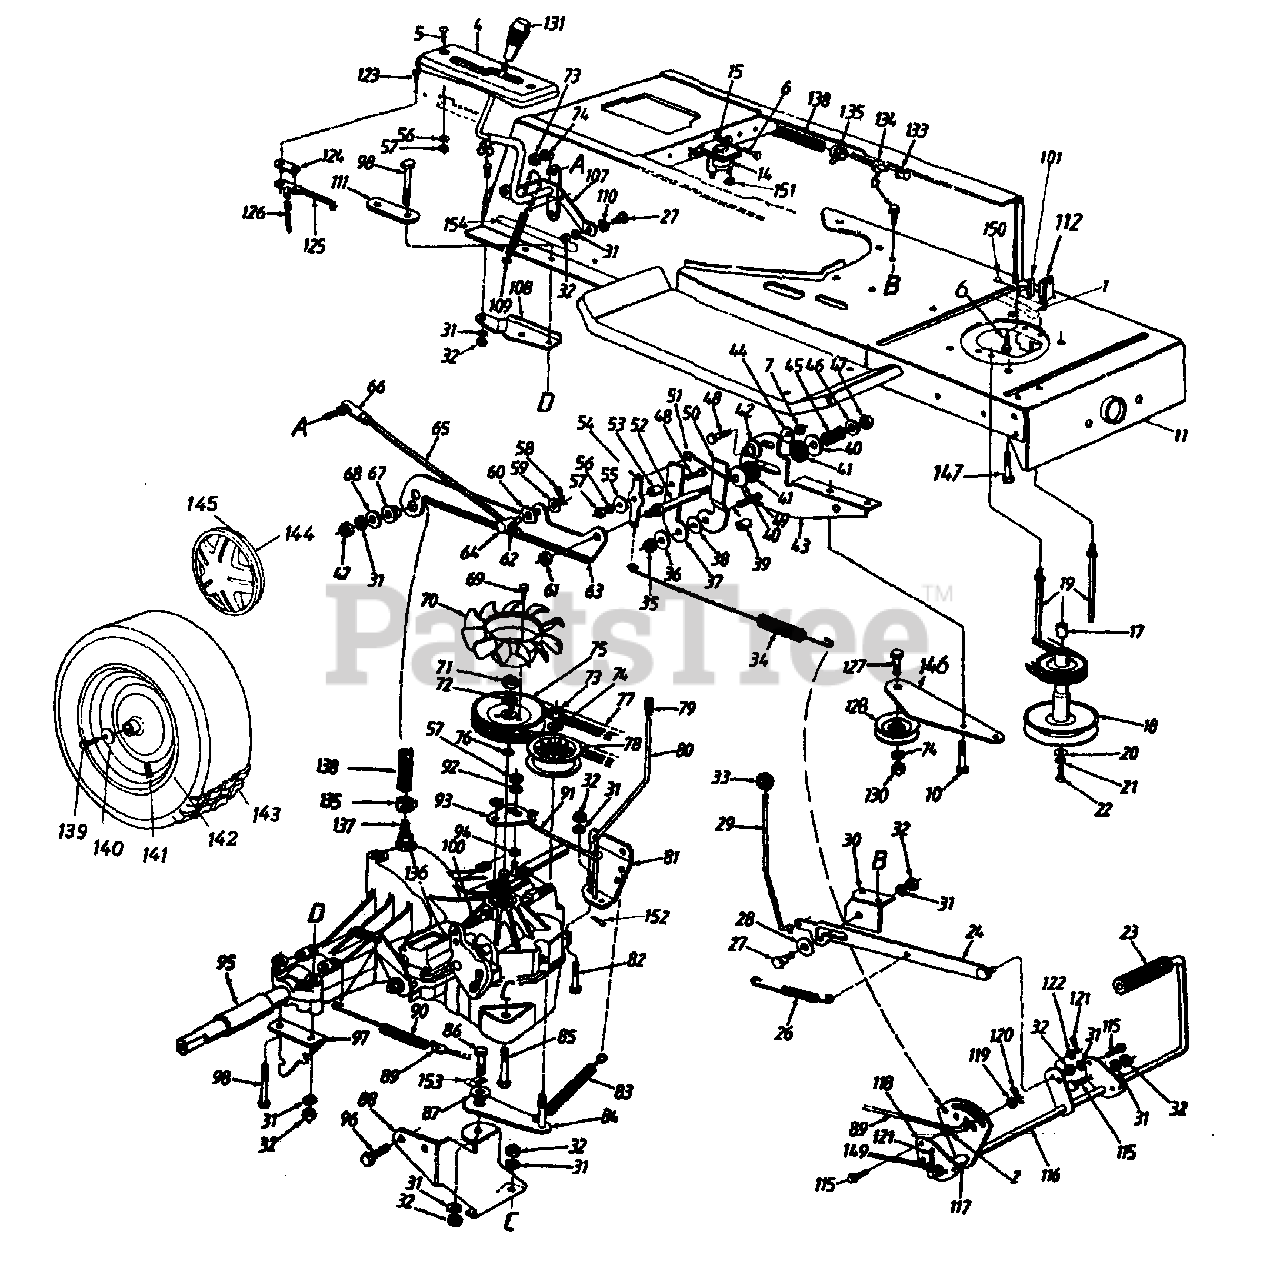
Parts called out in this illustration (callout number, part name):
1	Spring Switch
2	Hex Sems Nut 5/16-18 Thd.
4	Index Bracket
5	Pan Hd. Mach. Scr. 1/4-20 x .75"
6	Hex Wash. Hd. TT-Tap Scr.
7	Hex Nut 1/4-28 Thd.
10	Hex. Bolt 1/4-28 x .62" Lg.
14	Solenoid
15	Ext. L-Wash. 1/4" I.D.
18	Engine Pulley
19	Belt Guard Stud 4.75" Lg.
20	Fl-Wash. 7/16" I.D. x 1.25" O.D.
21	L-Wash. 7/16" I.D.
22	Hex Bolt 7/16-20 x 1.25" Lg.
23	Foot Pad
27	Shld. Bolt .437" Dia. x .268"
28	Fl-Wash. 7/16" I.D. x 1-3/8" O.D.
29	Lock-up Rod
31	L-Wash. 5/16" I.D.
32	Hex Nut 5/16-18 Thd.
33	Ball Knob
34	Neutral Return Spring
35	Hex Nut 5/16-24 Thd.
36	Fl-Wash. .344" I.D. x 1" O.D.
37	Scissor-Flat
38	Fl-Wash. .33" I.D. x 1.25" O.D.
40	Bell-Wash. .4" I.D. x 1.13" O.D.
41	Friction Washer
42	Centering Gauge Spacer
43	Neutral Return Mtg. Brkt.
44	Bell-Wash. .265" I.D. x.75" O.D.
45	Comp. Spring 1.19" Lg.
46	Fl-Wash. .26" I.D. x .72" O.D.
47	Hex Nut 5/16-24 Thd.
48	Hex Bolt 1/4-28 x 1" Lg. (Gr. 5)
49	Rib Neck Bolt 5/16-24 x .84" Lg.
50	Scissor-Offset
51	Neutral Return Rod
52	Friction Disc Stud
53	Shld. Spacer
54	Neutral Return Lever
55	Fl-Wash. .265" I.D. x 1" O.D.
56	L-Wash. 1/4" I.D.
57	Hex Nut 1/4-20 Thd.
58	Hairpin Clip
59	Fl-Wash. .375" I.D. x.87" O.D.
60	Spring Wash. .39" I.D.
61	Hex L-Nut 3/8-24 Thd.
62	Hex Jam Nut 3/8-24 Thd.
63	Neutral Return Brkt.
64	Ferrule 3/8-24 Thd.
65	Control Rod
66	Ball Joint 3/8-24 Thd.
67	Shld. Spacer .5" Dia. x .27" Lg.
68	Fl-Wash. .349" I.D. x .879" O.D.
69	Hex Tap Scr. #12 x .62" Lg.
70	Fan
71	Hex Nut 1/2-20 Thd.
72	L-Wash. 1/2" I.D.
73	Hex Nut 3/8-24 Thd.
74	L-Wash. 3/8" I.D.
75	Transmission Pulley
76	Wire Ring
77	V-Belt
78	Fl-Idler Pulley 2.75" O.D.
79	Rod End Grip
80	Bypass Control Lever
81	Transaxle Support Brkt.- L.H.
82	Hex Bolt 5/16-18 x 1.25" Lg.
83	Ext. Spring 6.12
86	Hex Bolt 5/16-18 x .75" Lg.
87	Shld. Spacer .5" Dia. x .27" Lg.
88	Transaxle Support Brkt.- R.H.
89	Brake Rod 24.94" Lg.
90	Ext. Spring
91	Bypass Actuator Rod
92	Fl-Wash. .281" I.D. x.5" O.D.
93	Bypass Adjustment Brkt.
94	External L-Wash. 1/4" I.D.
95	Sleeve .758" I.D. x 1" O.D.
96	Hex. TT-Tap Scr .5/16-18x.62"
100	Hex Bolt 5/1 6-24 x 1" Lg.
101	Hex Wash. Hd. AB-Tap Scr.
107	Speed Control Lever Ass'y.
110	Spr-Wash. .445" l.O. x.75" O.D.
112	Safety Switch (Clutch)
115	Hex TT-Tap Scr. 5/16-18 x 7/8"
120	Cotter Pin 3/32" Dia.
121	Cotter Pin 1/8" Dia.
122	Fl-Wash. .385" I.D. x .62" O.D.
123	Hex AB-Tap Scr. #8 x .5" Lg.
124	Insulator Nut Plate
125	Reverse Safety Switch
126	Extension Wire
127	Hex Bolt 3/8-16 x 1.5" Lg.
128	Idler Pulley
130	Hex Nut 3/8-16 Thd.
131	Shift Knob
134	Plastic Vent
135	Clamp
137	Hose Fitting
138	Fuel Line 18" Lg.
139	Hex Bolt 5/16-24 x .75" Lg.
140	Bell-Wash. .345" I.D. x.88" O.D.
141	Air Valve
144	Hub Cap
145	Spring Clip
146	Idler Bracket
147	Hex TT-Tap Scr. 3/8-16 x 1.25"
